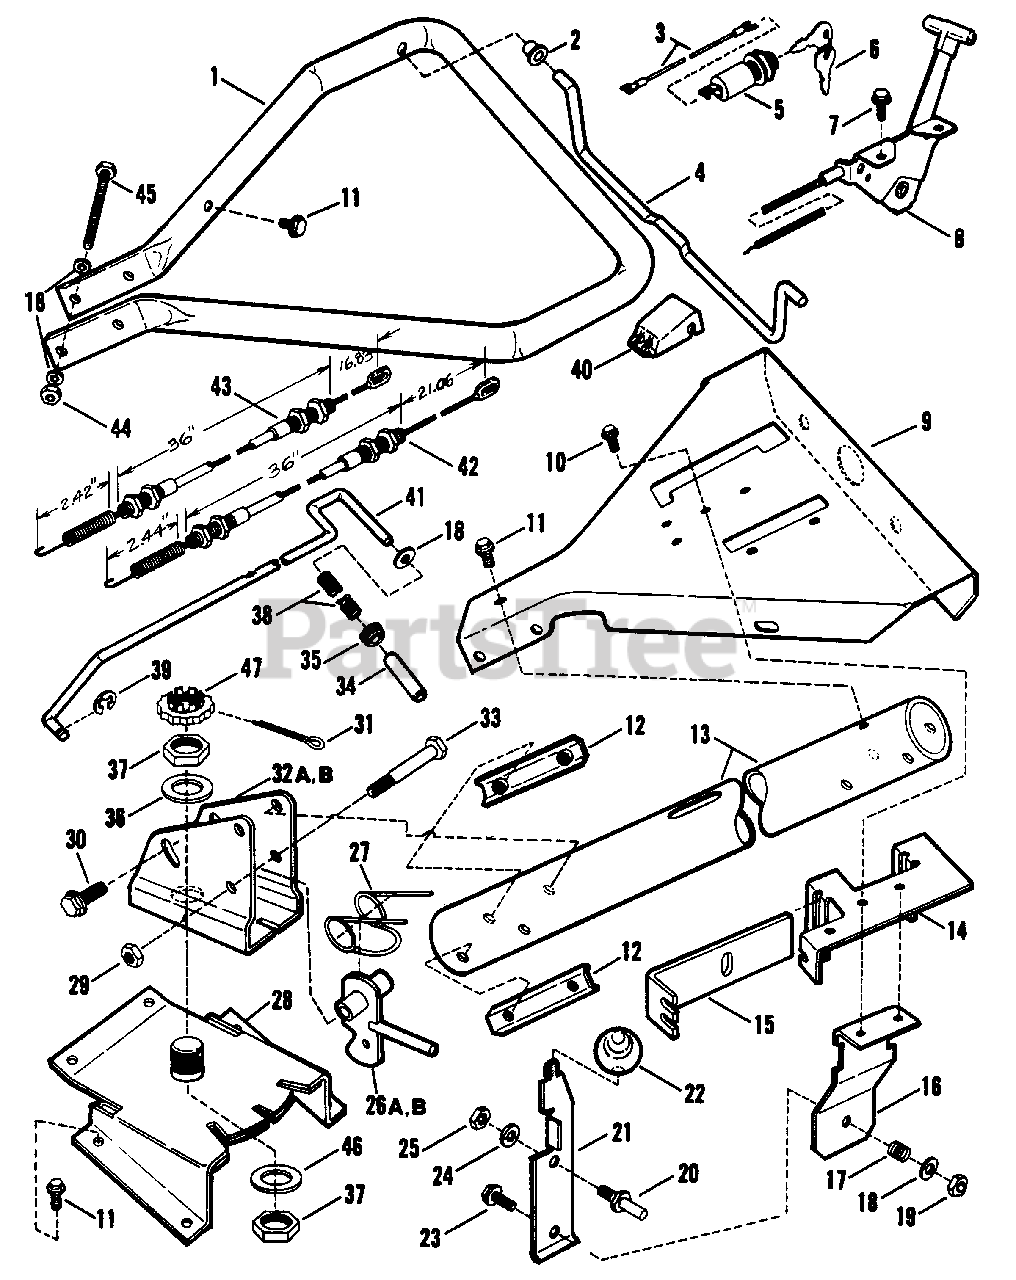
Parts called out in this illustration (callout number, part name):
1	BAR, Handle
2	BUSHING
3	(NLA) WIRE, Ground
5	SWITCH, Ignition
6	KEY, Switch (pair)
7	SCREW, 1/4-20 x 3/8" Hex Washer Self-Tap
8	CONTROL, Throttle
9	PANEL, 8 HP
10	SCREW, 1/4-20 x 1/2" Hex Washer Self-Tap
11	SCREW, 5/16-18 x 1/2" Hex Washer Self-Tap
12	PLATE, Tap Nut
13	TUBE, Handle Bar Support
14	BRACKET, Cable
15	SLIDE
16	(NLA) BRACKET
17	SPRING
18	WASHER, 5/16" SAE Flat
19	NUT, 5/16-24 Hex Center Lock
20	STUD, Shift
21	HANDLE, Clutch
22	KNOB
23	SCREW, 5/16-24 x 1-1/4" Hex Head Cap, Grade 2
24	WASHER, 5/16" Split Lock
25	NUT, 5/16-18 Hex
26A	LATCH
26B	LATCH
27	SPRING
28	BRACKET, Latch
29	NUT, 3/8-24 Hex Center Lock
30	BOLT, 3/8-16 x 3/4" Hex Flange Lock
31	PIN, 5/32 x 1-1/4" Cotter
32A	BRACKET, Handle
32B	(NLA) BRACKET, Handle
33	SCREW, 3/8-24 x 2-1/2" Hex Head Cap
34	GRIP, Handle Release
35	BUSHING
36	WASHER, 13/16" Flat
37	NUT, 3/4-16 Hex Jam Lock
38	SPRING
39	E-RING
40	CLIP, Cable
41	ROD, Handle Release
42	CABLE, Traction Control
43	CABLE, Tine Control
44	NUT, 5/16-18 Hex Center Lock
45	SCREW, 5/16-18 x 3" Hex Head Cap, Grade 5
46	WASHER, 3/4" I.D. Flat
47	RETAINER, Nut Locking
